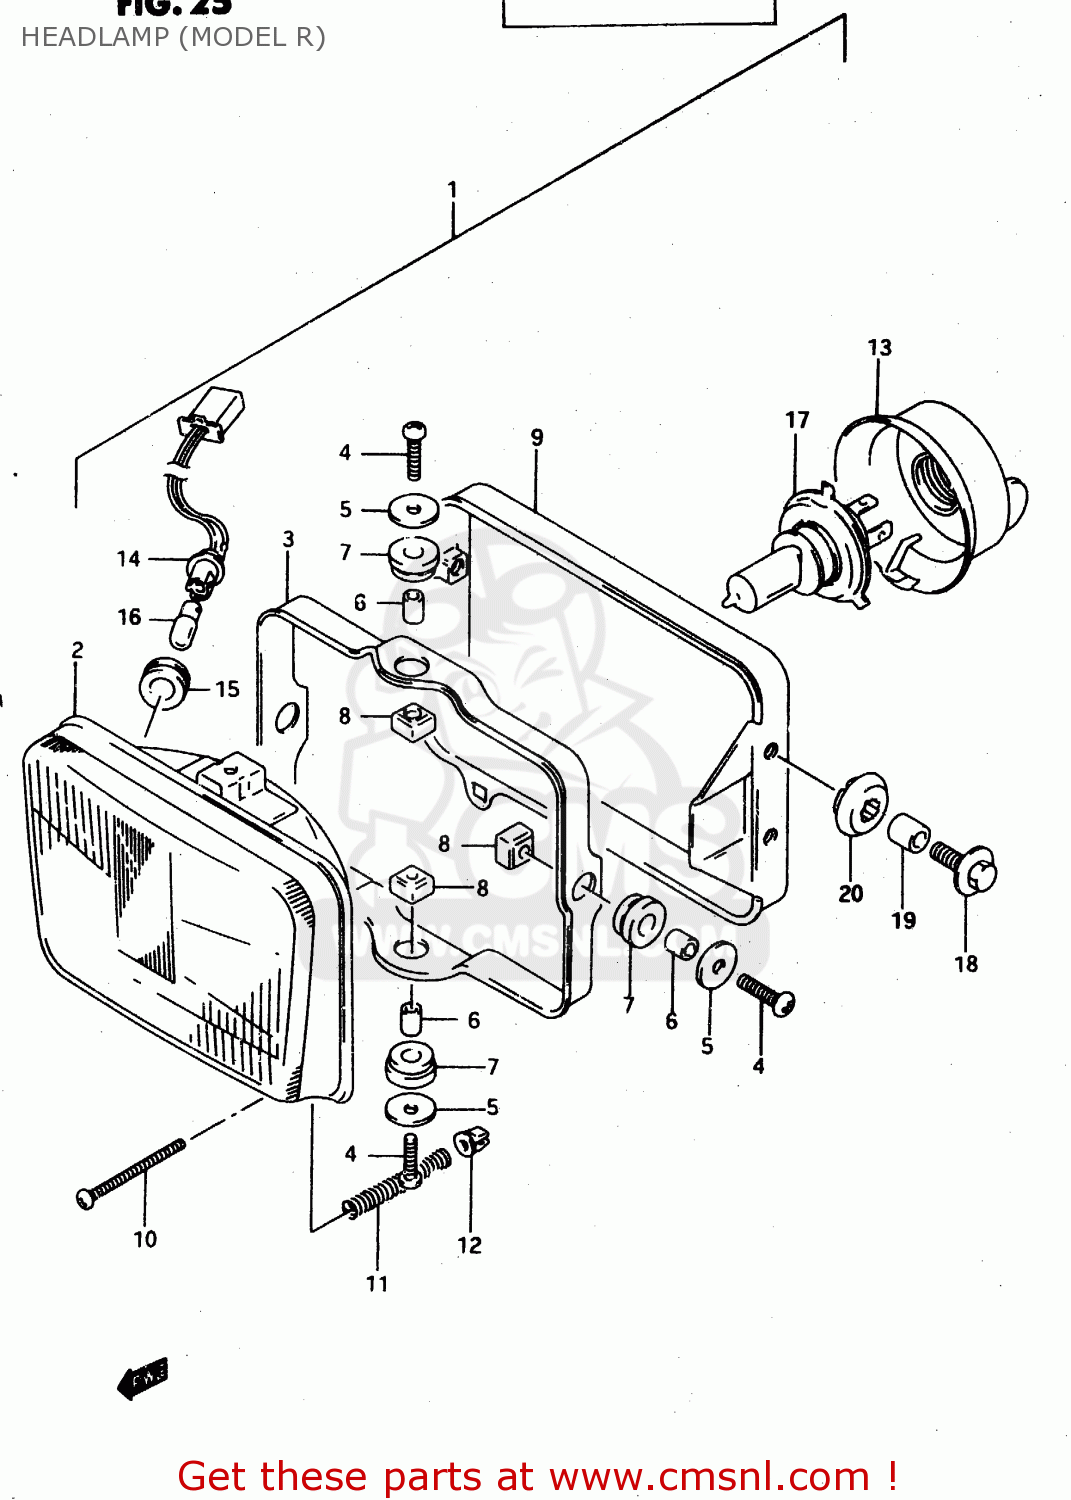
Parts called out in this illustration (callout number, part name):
1	HEADLAMP ASSY
2	UNIT ASSY
3	RING,MOUNTING
4	SCREW,HEADLAMP ADJUST
5	WASHER
6	SPACER
7	CUSHION
8	NUT
9	HOUSING
10	SCREW(4X45)
11	SPRING,ADJUSTING
12	NUT,ADJUSTING
13	COVER,SOCKET
14	CORD,POSITION
15	JOINT,RUBBER
16	BULB(12V4W)
17	BULB(12V60/55W,H4)
18	BOLT(6X20)
19	SPACER (6.8X10X10)
20	CUSHION
